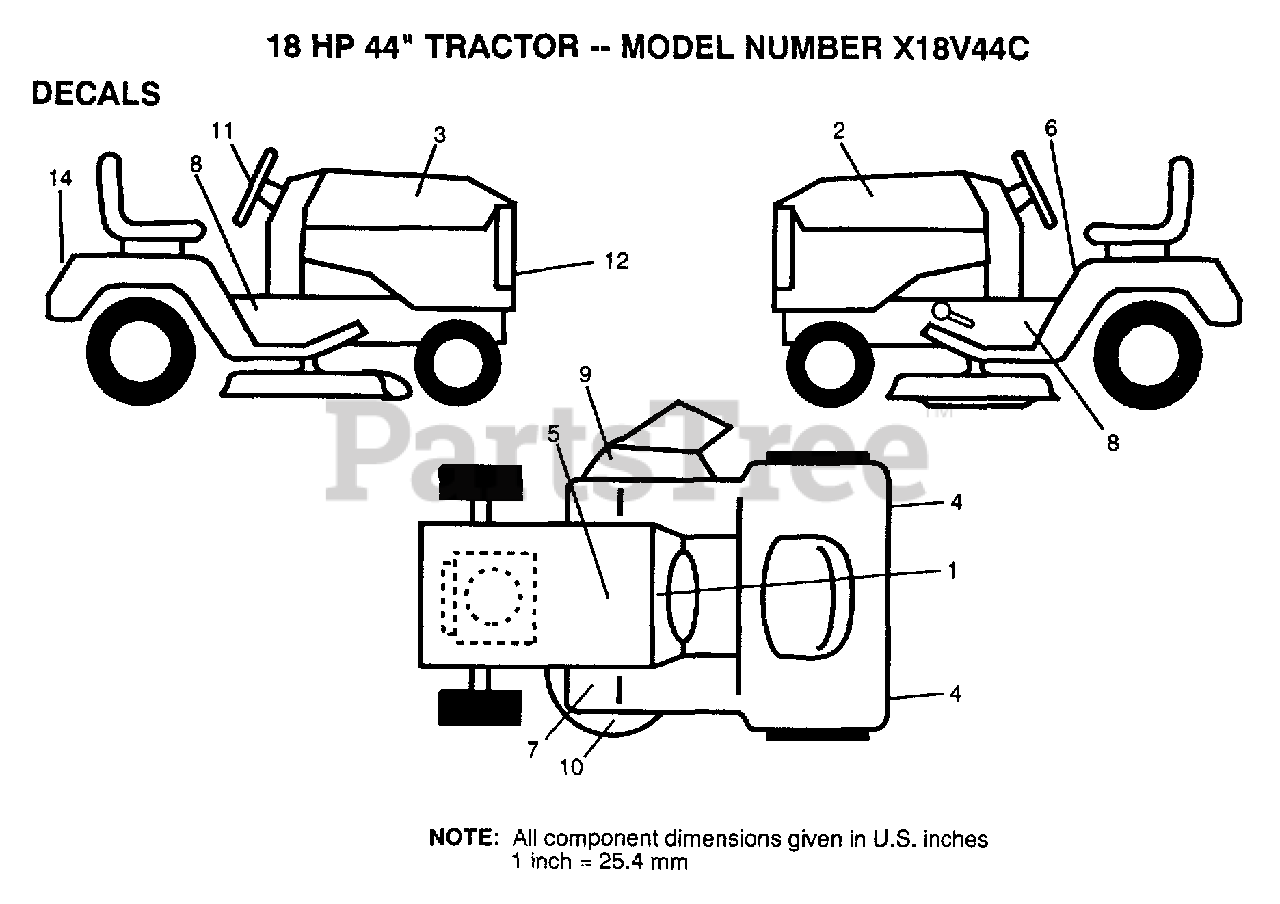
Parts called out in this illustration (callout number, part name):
3	"DECAL,HOOD RH "
4	REFLECTOR-TAIL YT
5	DECAL
6	DECAL
7	DECAL T
8	DECAL, CHASSIS
9	DECAL WARNING
10	DECAL-INST YT
11	"DECAL,STR WHL"
12	"DECAL,GRILL "
14	"DECAL,LOGO"
